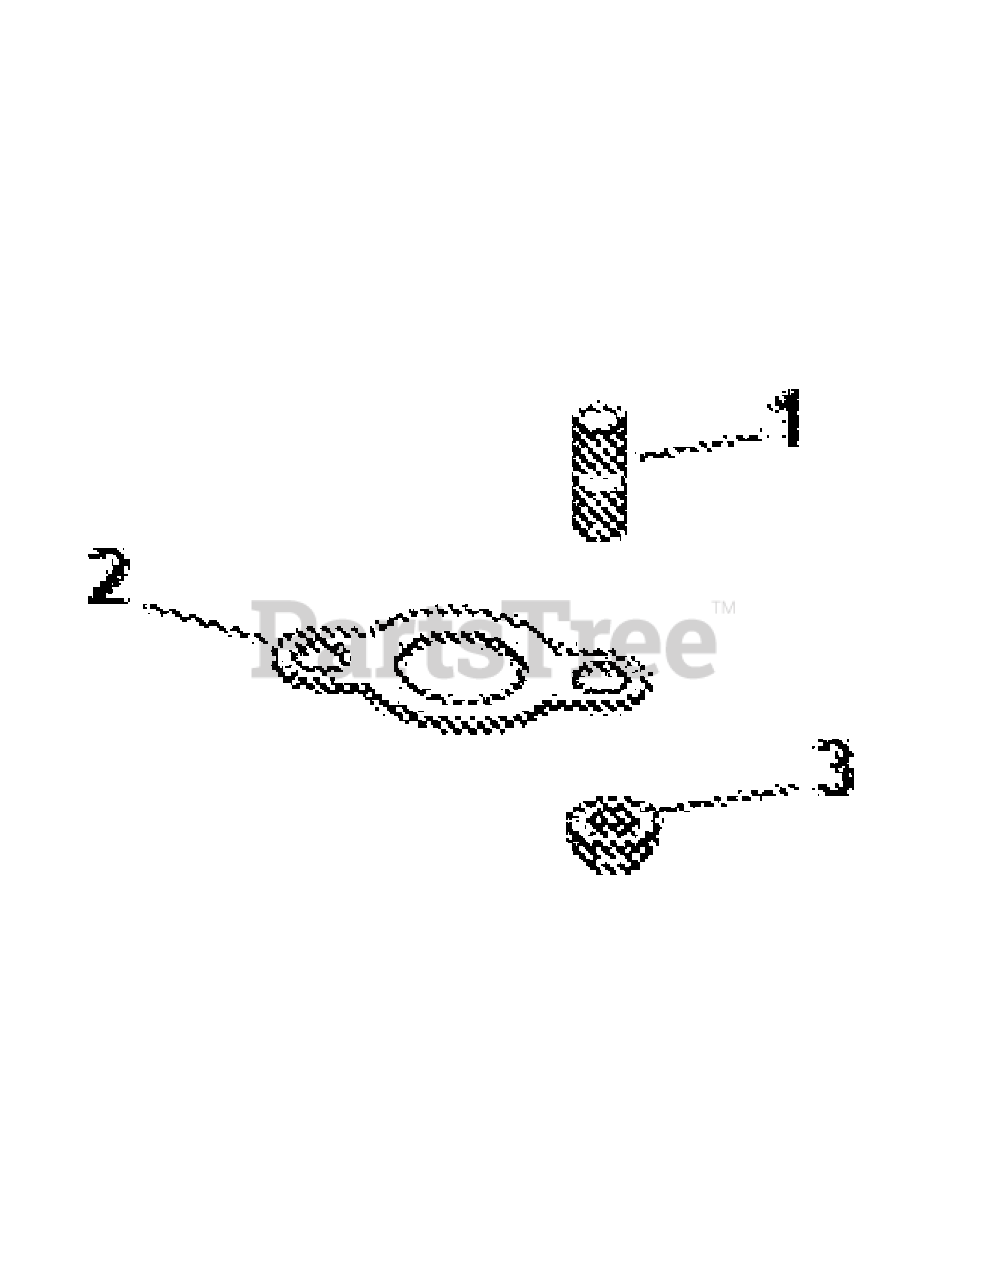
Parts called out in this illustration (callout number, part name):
1	Stud (M8 x 1.25 x 33)
2	Exhaust Gasket
3	Muffler Mounting Nut (M8 x 1.25)
